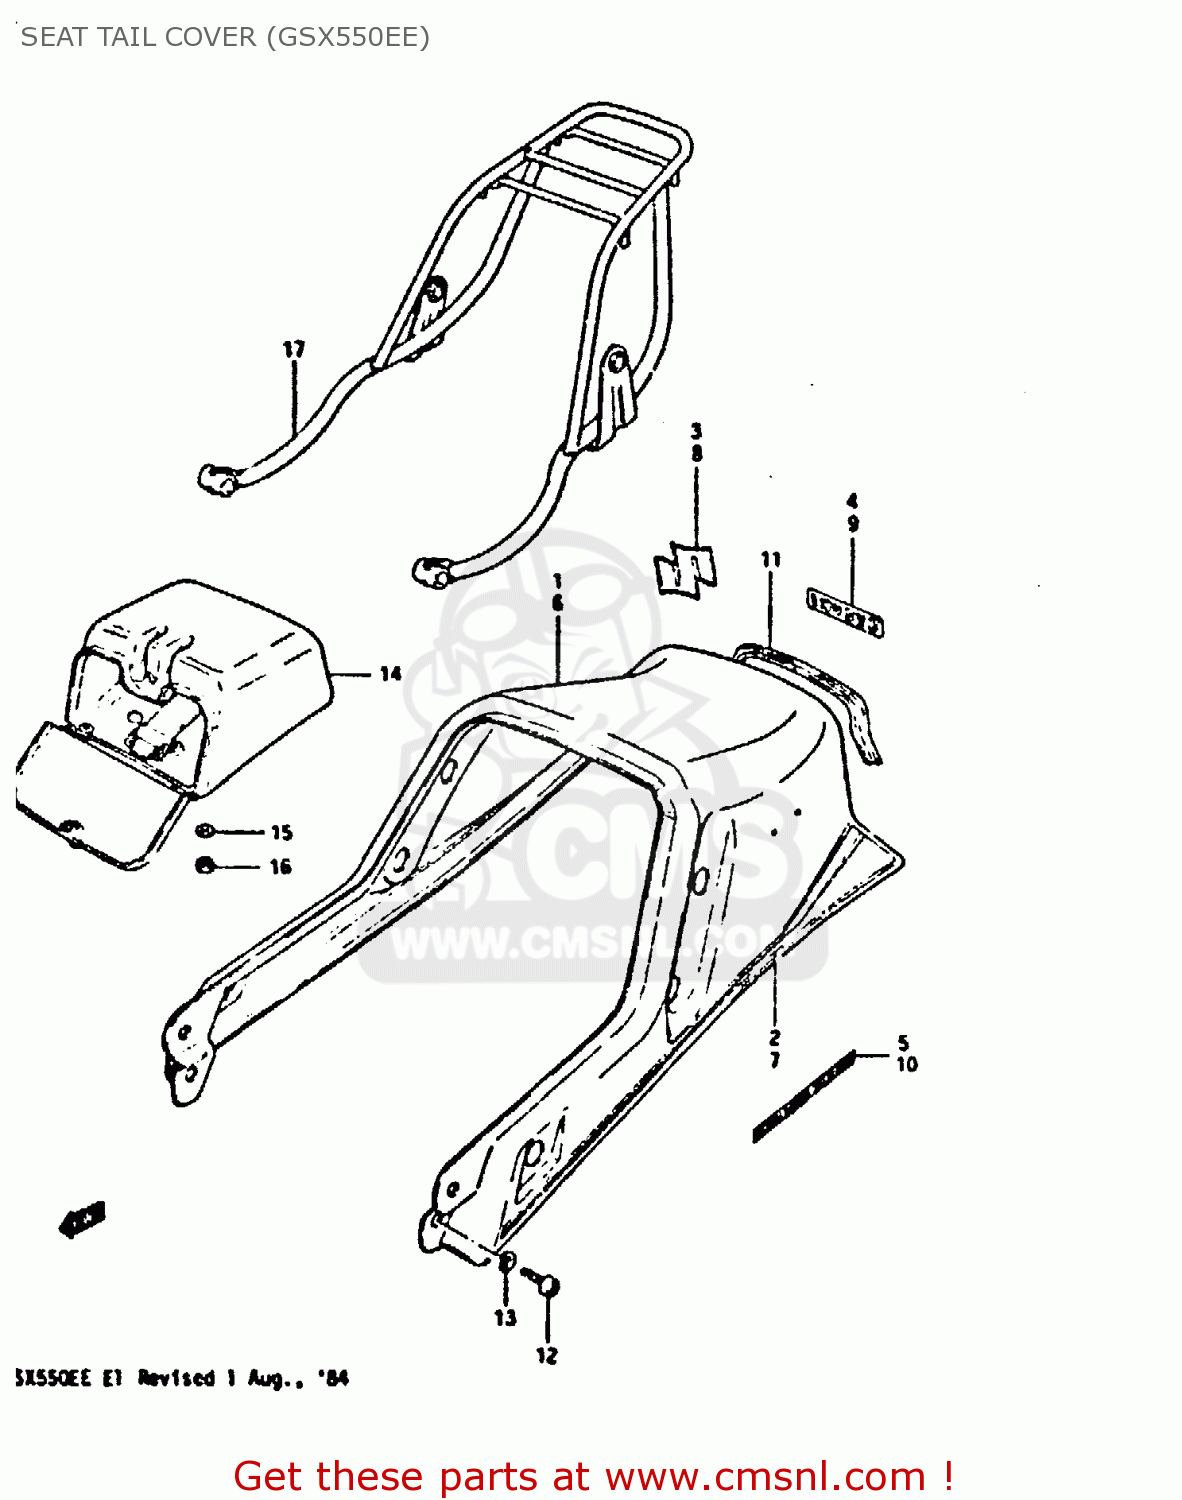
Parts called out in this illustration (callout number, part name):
1	TAIL COVER, SEAT (BLACK)
2	TAPE SET, SEAT TAIL COVER
3	EMBLEM, "S" MARK
4	EMBLEM (GOLD)
5	EMBLEM
6	TAIL COVER, SEAT (RED)
7	TAPE SET, SEAT TAIL COVER
8	EMBLEM,SEAT TAIL (S)
9	EMBLEM(WHITE)
10	EMBLEM
11	BLIND,SEAT TAIL COVER
12	SCREW
13	LOCK WASHER
14	BOX,SEAT TAIL
15	WASHER
16	NUT
17	CARRIER, SPORTS
